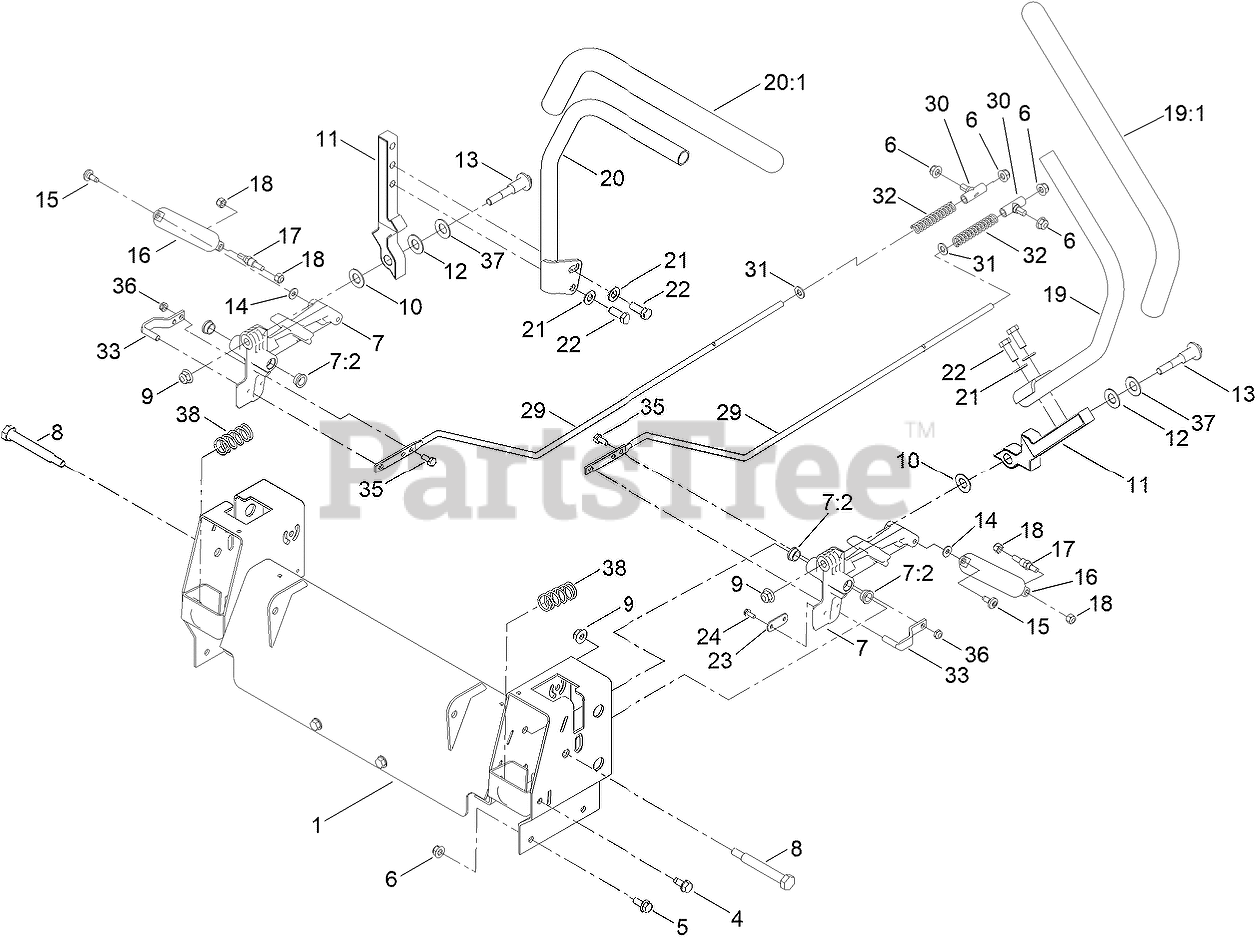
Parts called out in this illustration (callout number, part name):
1	CONTROL BOX ASM
4	SCREW-HWHTF
5	SCREW-HHF
6	NUT-HF
7	ACTUATOR ARM ASM
7:2	BUSHING-FLANGE
8	BOLT-PIVOT
9	NUT-HF, NI
10	WASHER-NYLON
11	ARM-CONTROL
12	WASHER
13	BOLT-PIVOT
14	WASHER
15	SCREW-SHOULDER
16	DAMPER-NON CAVITATING
17	STUD-DAMPER
18	NUT-HEX
19	HANDLE-CONTROL, LH
20	HANDLE-CONTROL, RH
21	WASHER-FLAT
22	SCREW-HH
23	PLATE-STOP,HYDRO
24	SCREW-TAPTITE
29	ROD-HYDRO
30	MOUNT-ROD, HYDRO
31	WASHER-PLAIN
32	SPRING-COMPRESSION
33	PIN-ROD, HYDRO
35	SCREW-HH
36	NUT-HEX
37	WASHER-BELLEVILLE
38	SPRING-RETURN
